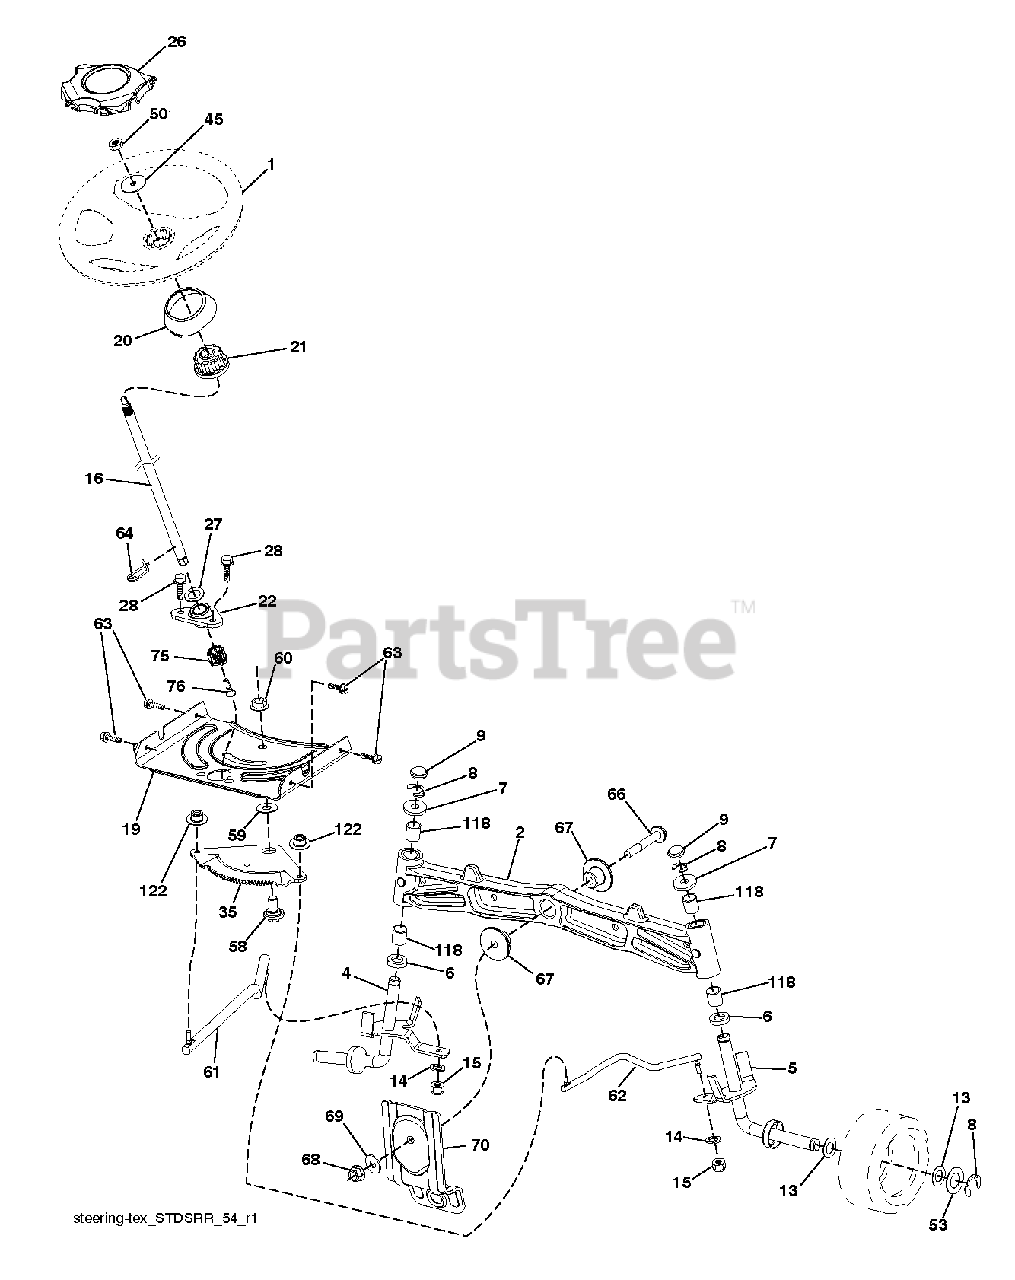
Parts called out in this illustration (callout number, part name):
1	WHEEL.STEERING.STDSRR.BLK/OV
2	AXLE.SVC.ASM CAST IRON.TEX
4	SPINDLE.WELDED.LH.15"TEX
5	SPINDLE.WELDED.RH.15"T
8	RING CLIP
9	CAP.SPINDLE
14	WASHER, LOCK 3/8
15	NUT CROWNLOCK 3/8-24
16	Steering Shaft Service Kit
19	PLATE.STEER.DDL.NLT/NG
21	Steering Shaft Adapter Kit
22	Steering Shaft Service Kit
26	CAP.WHL.STRNG.STDSRRD.SRS.BLK
27	WASHER LT
28	SCREW, 3/8-16X3/4
35	GEAR.SECTOR.PLATE.DDL.
45	WASHER 9/16"ID, 2 3/8"OD
50	NUT LOCK FLG 3/8-16 UNC
53	WASHER.HARDENED
58	BOLT.SHOULDER.SECTOR.P
59	WASHER.THURST.SECTOR.S
60	NUT FLANGE LOCK 5/8-11
61	DRAGLINK.LH.BALLSTUD.D
62	DRAGLINK.RH.BALLSTUD.D
63	SCREW
64	RETAINER.CLIP.SPRING.S
66	BOLT HEX FGHD 7/16-14 X 3 SERR
67	BUSHING.PM.FRONT AXLE
68	NUT.LOCK.FLANGE.7/16
69	WASHER.1.5X.505X.118
70	Deck Suspension Bracket, Front RR
75	Steering Shaft Pinion Kit
76	Screw Head Socket Lrvb
118	BUSHING, AXLE CAST
